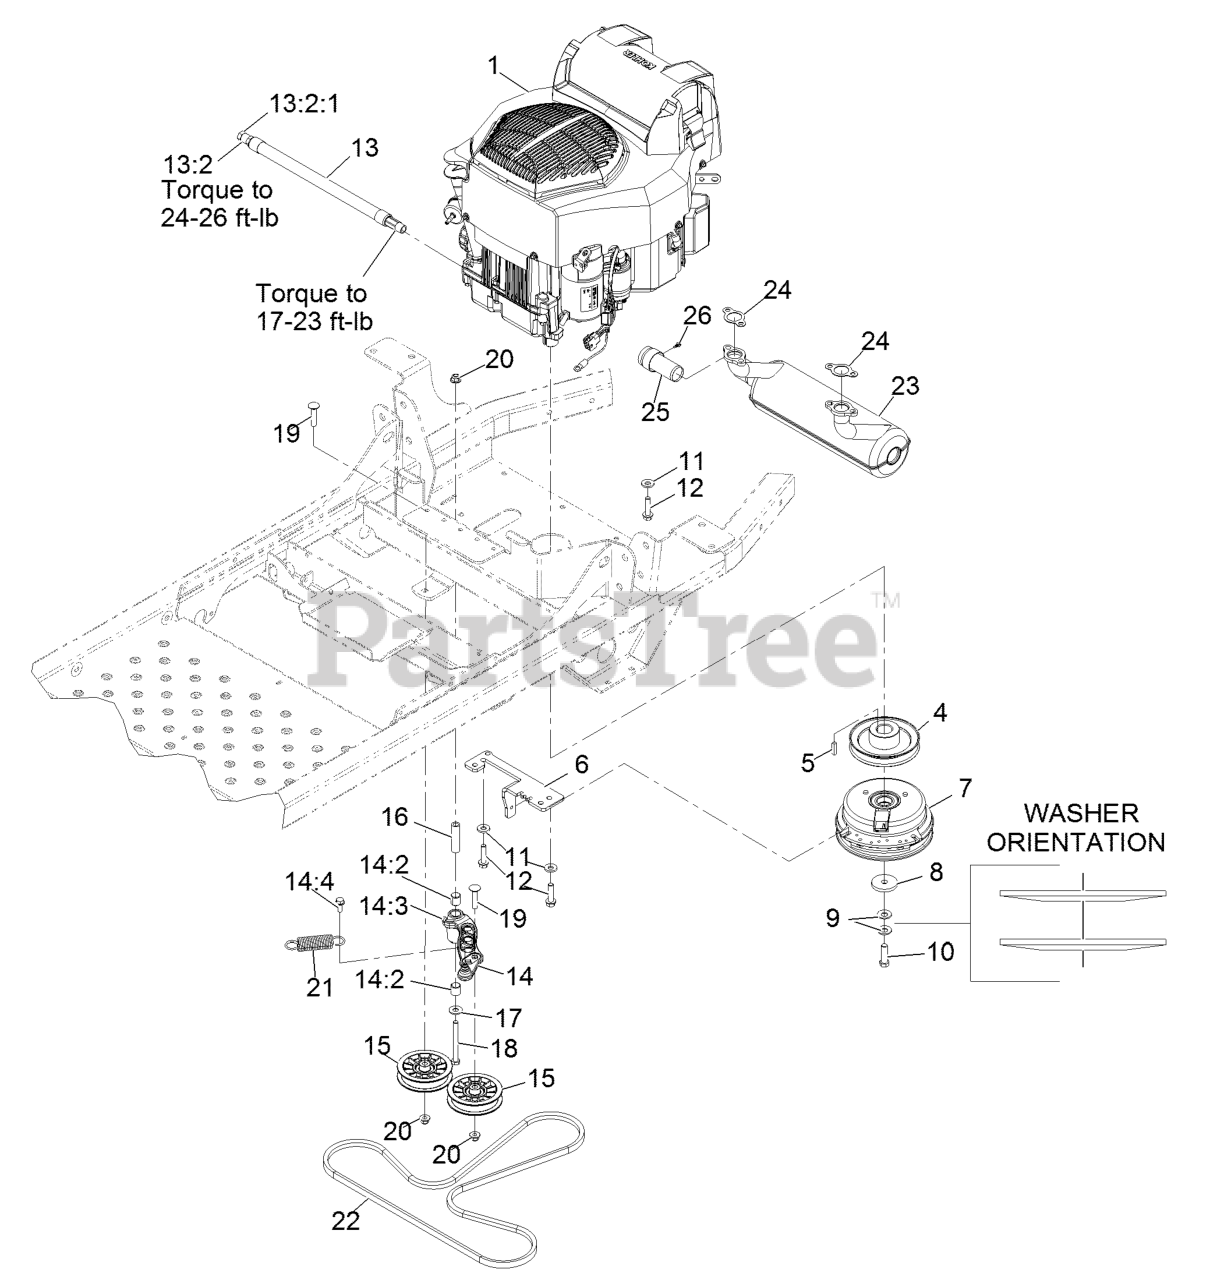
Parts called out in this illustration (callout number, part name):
4	SHEAVE-PUMP, DRIVE
6	ANCHOR-CLUTCH
8	WASHER-CLUTCH
9	WASHER-SPRING
10	SCREW-HH 7/16-20 X 1 1/2 W/LOCTITE
11	WASHER-BELLEVILLE
12	SCREW-HWH
13	OIL DRAIN HOSE ASM
13:2	PLUG-HH
13:2:1	O-RING
14	IDLER ARM ASM
14:2	SLEEVE-BEARING
14:3	FITTING-GREASE, 90 DEG
14:4	SCREW-THD ROLL, HWH
15	PULLEY-FLAT IDLER
16	BUSHING-PIVOT, IDLER
17	WASHER-FLAT
18	SCREW-CARR
19	SCREW-CARR
20	NUT-HF, NI
21	SPRING-EXTENSION
22	V-BELT
23	MUFFLER, KOHLER
24	GASKET-EXHAUST
25	ARRESTOR-SPARK
26	SCREW-HWH
